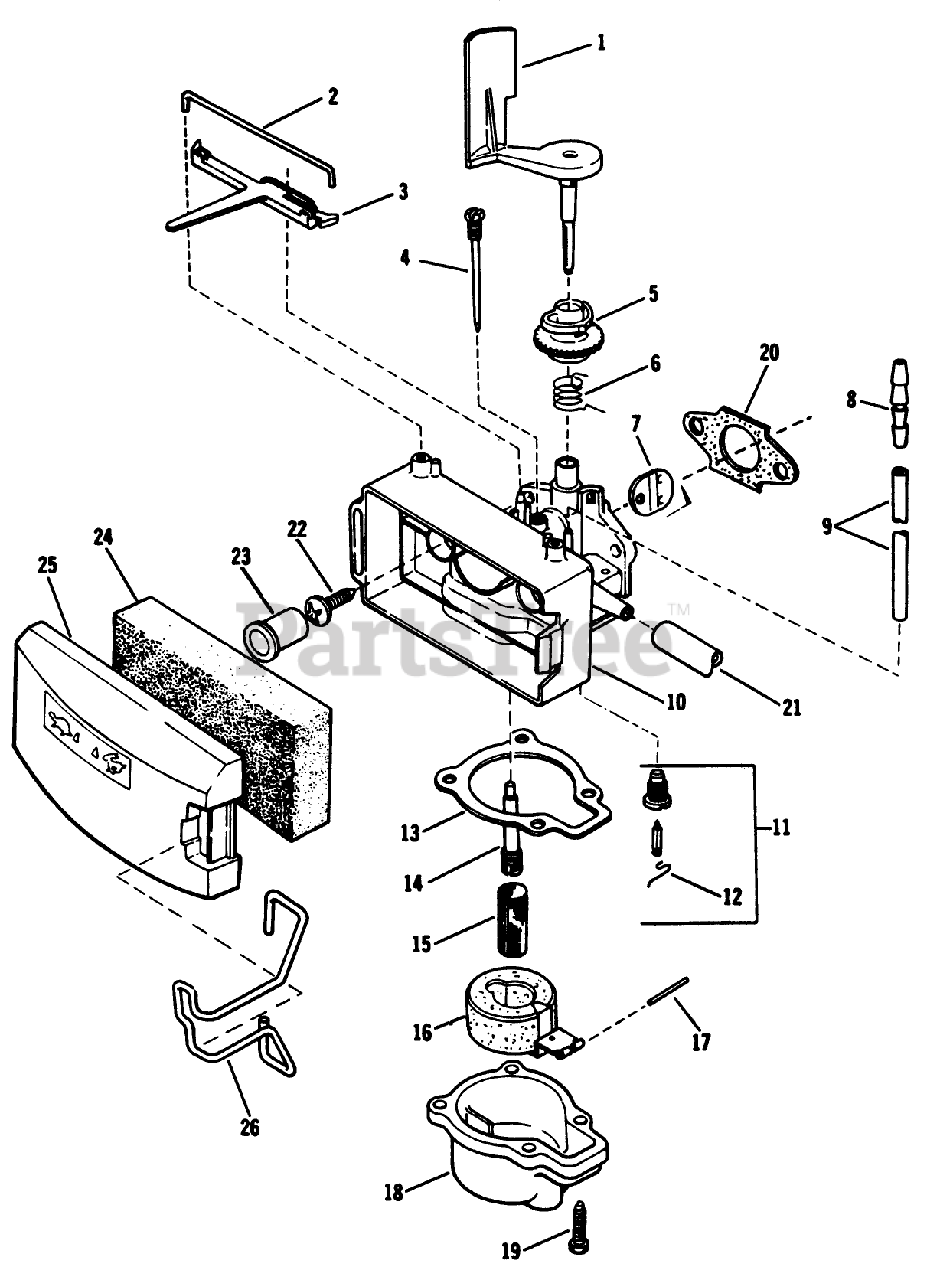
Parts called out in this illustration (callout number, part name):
2	RETAINER
3	LEVER S
4	NEEDLE ADJ. AY S
5	COLLAR-ADJUST, AIRVANE
6	SPRING,THROTTLE S
7	DISC S
8	REDUCER-CONNECTOR
9	TUBING S
10	CARB BODY S
15	FILTER-FUEL VS
19	SCREW-HH
20	GASKET CARB S
21	GAS LINE
22	SCREW
26	RETAINER-COVER, FILTER
